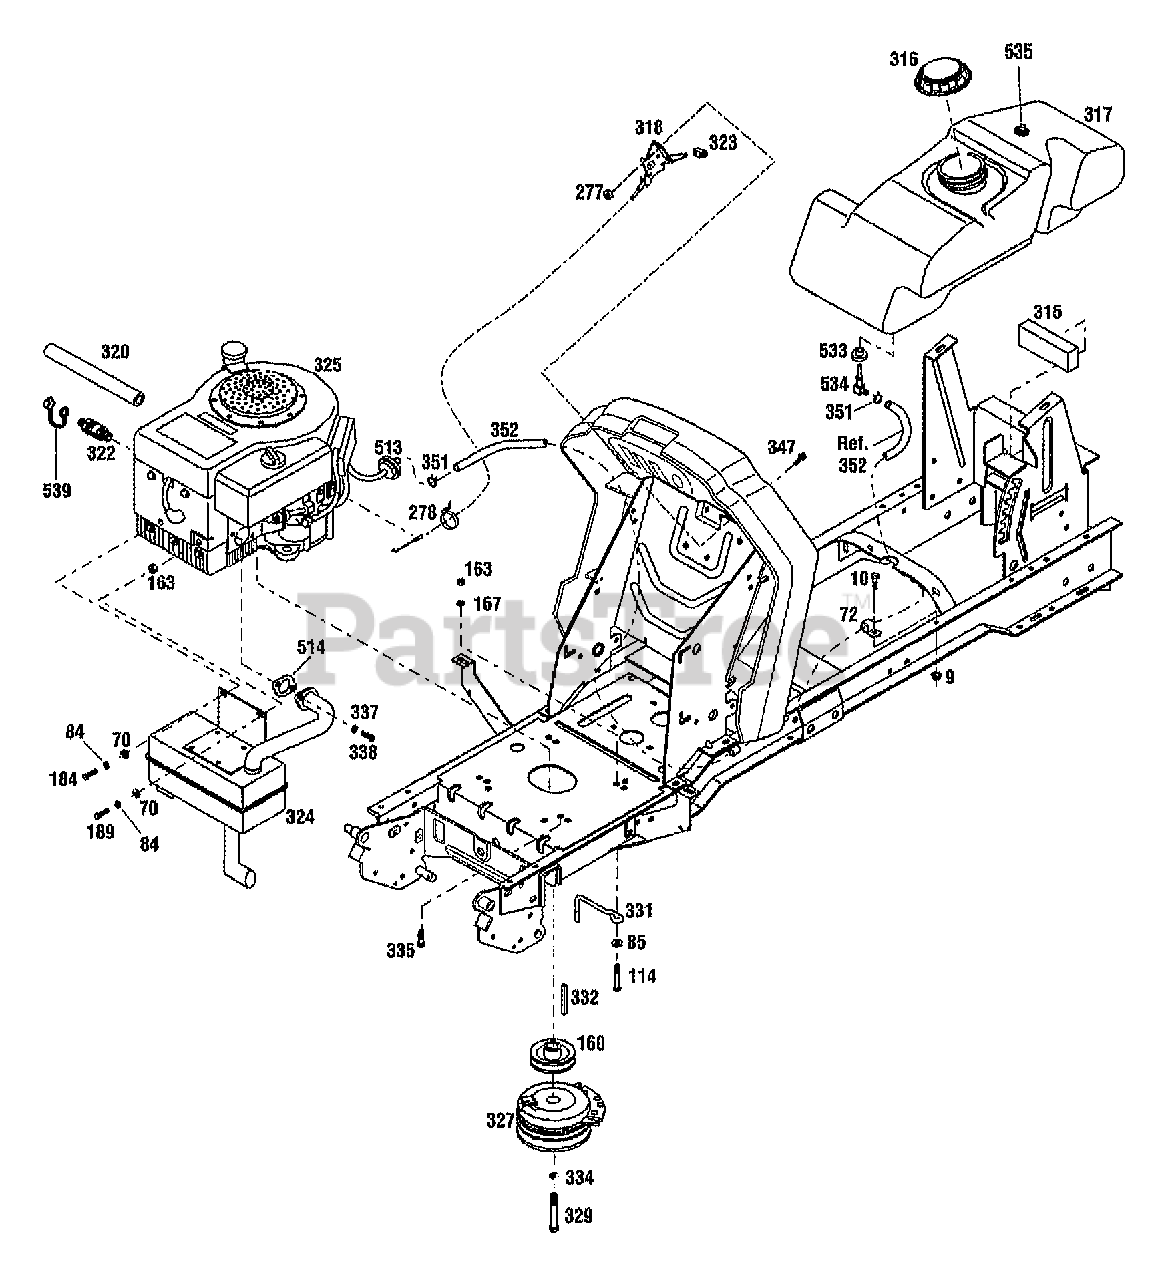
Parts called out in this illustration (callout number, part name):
9	NUT-HFLK 5/16-18 ZP
10	SCR-HHC 5/16-18X.75 GR 5 ZP
70	WASHER-FLAT 1/4 SAE
72	CLAMP-WIRE
84	WASHER-LK .25 ZP
85	WASHER-FLAT 3/8 SAE
114	SCR-THRD FRM 3/8-16X1.50
160	PULLEY-ENGINE
163	NUT-HEX 3/8-16 ZP
167	WASHER-LK .375 @ DEPL
184	SCR-HH 1/4-20 X .875
189	SCR-HH 1/4-20X1.25
277	NUT W/LKWASHER 10-24 ZP
278	TIE-CABLE NYLON BLACK
315	PAD-FUEL TANK
316	CAP-FUEL
317	TANK-FUEL
318	CONTROL-THROTTLE
320	HOSE-OIL DRAIN
322	ASSM-OIL VALVE
324	MUFFLER
325	ENGINE, 13 HP
327	CLUTCH-ELECTRIC
329	SCR-HH 7/16-20X3 G5 ZP
331	CLUTCH-RETAINER
332	KEY-.25 SQ X 1.5
334	WASHER-LK .438 ZP
335	SCR-HH 3/8-16X1.0 THDFM
337	WASHER-LOCK
338	SCR-HXSKT 5/16-18X.75 BO
347	SCR-MACH 10-24X3/4
351	CLAMP-HOSE
352	LINE-FUEL
513	FILTER-FUEL
514	MUFFLER GASKET
533	BUSHING-RUBBER
534	ELBOW-90 DEG (FUEL LINE)
535	VENT-FUEL TANK
539	CAP-OIL DRAIN
